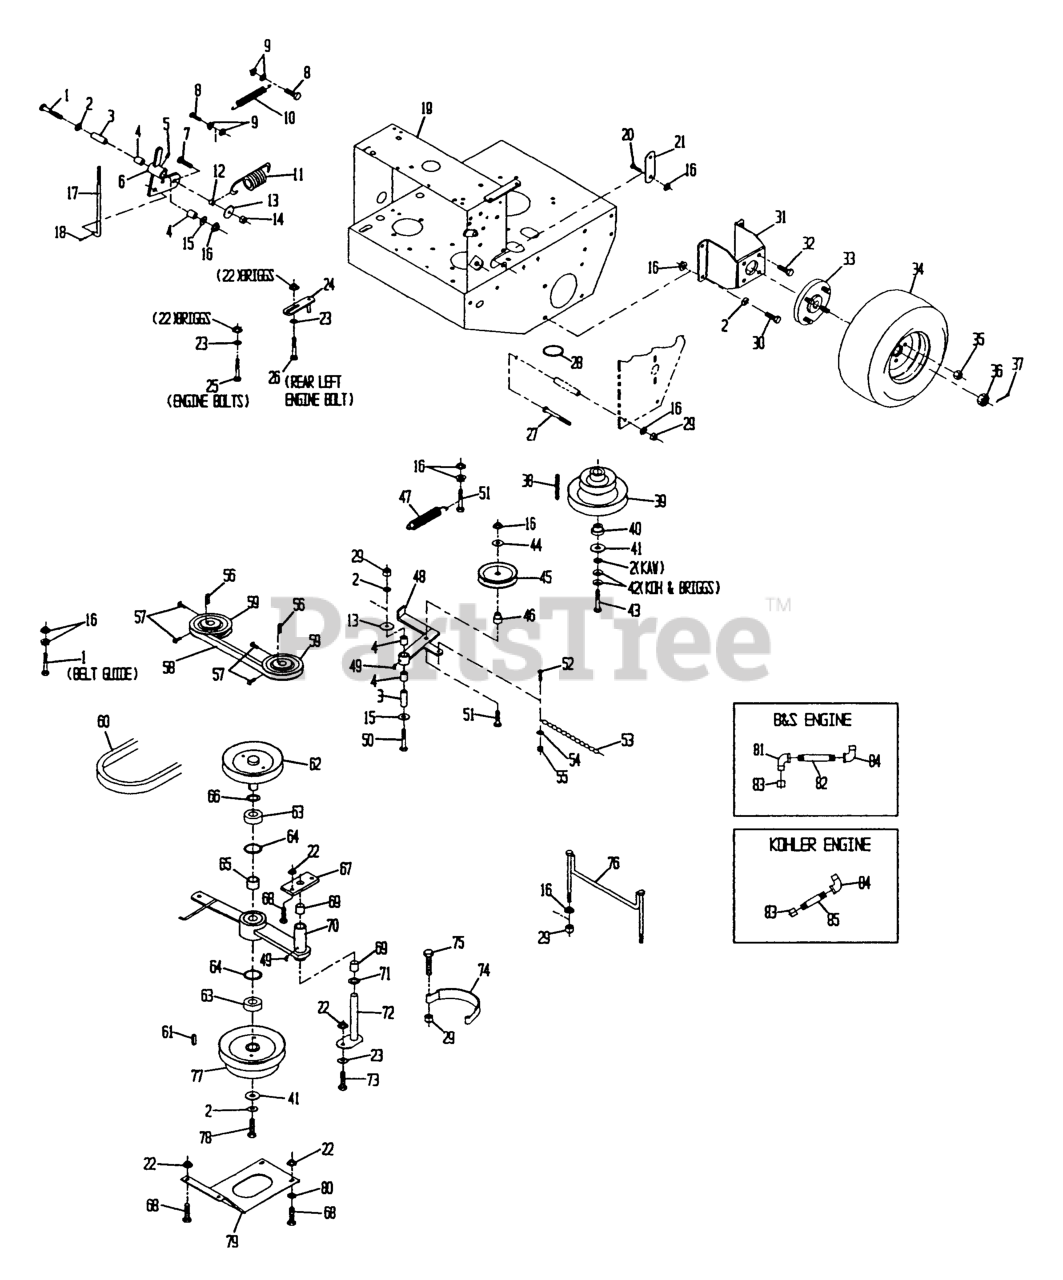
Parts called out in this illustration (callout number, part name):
3	BUSHING
4	SLEEVE-BEARING
10	SPRING,EXTENSION
11	SPRING,BELT TENSION
12	SPACER,CLUTCH ANCHOR
17	LINKAGE,LOWER
18	PIN-COTTER
21	ARM-LIFT, DECK
23	WASHER-SPRING
24	GUIDE-BELT
28	RING-SPLIT
31	WLD,MOTOR MOUNT 36
37	PIN-COTTER
38	KEY,MACH 1/4X1/4X2-5/8
39	SHEAVE,DRIVE
40	BUSHING,CLUTCH KEEPER
42	WASHER-SPRING
43	SCRW,CAP HH
46	BUSHING-IDLER
47	SPRING-EXTENSION
49	1481
52	SCREW-HSH
53	CHAIN-LINK, TWIST
57	SCREW-SET
59	SHEAVE ASM
60	BELT,BLADE CLUTCH
62	SHEAVE,6.13 W/SHAFT
63	BEARING,CLUTCH SHAFT
65	SPACER,CLUTCH BEARING
66	WASHER-SPACER
67	PLATE-CLUTCH PIVOT
69	SLEEVE,BEARING
71	WASHER-SPACER
72	WLD,PIN PIVOT
74	BAND,BRAKE BLADE
76	GUIDE - BELT
77	SHEAVE,6.13 W/HUB
78	SCRW,CAP HH
79	PLATE-GUARD
81	ELBOW-90 DEG
82	NIPPLE
83	CAP-HEX
84	FITTING-ELBOW-90
85	NIPPLE
